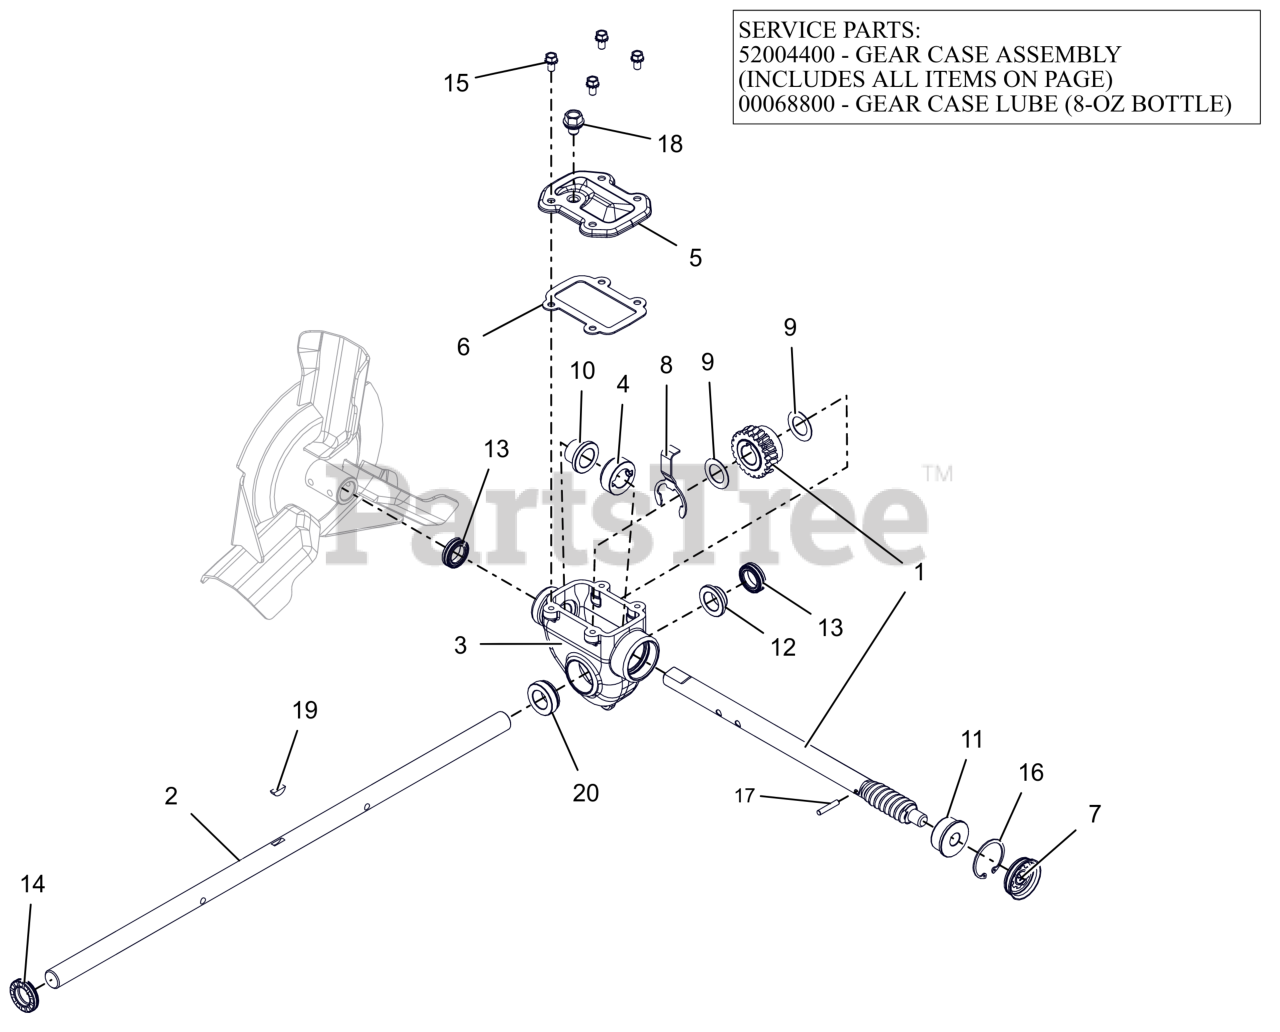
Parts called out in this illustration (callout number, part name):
1	SHAFT AND WORM GEAR ASSEMBLY
2	SHAFT, RAKE - 24" (.750 DIA)
3	GEARCASE, COMPACT MACHINED
3	GEAR CASE, 24" IRON SM TOP-LD
3	ARIENS L3 LUBE, 8 OZ BOTTLE
4	THRUST COLLAR, .75" ID SLIPFIT
5	COVER, TOP - COMPACT
6	GASKET, TOP - COMPACT GEARCASE
7	COVER, GEAR CASE 1.50"
8	BUSHING RETAINER, COMPACT
9	WSHR, FLT .760X1.225X.032 ZCC
10	BSHG-FLG .755X.878X.75X1.25
11	BSHG-FLG .503X1.303X.62X1.465
12	BSHG-FLG .755X.878X.424X1.25
13	SEAL-OIL .748X1.125X.312 TBC29
14	SEAL-OIL .748X1.300X.250 TBC29
15	BLT, SEMS .25-20X.50 G5 ZCC
16	RG-RTNG-INT 1.500X.050
17	PIN-STR .188X1.00 6150
18	SCR, .380-15X.500 W/SEAL WASHER
19	KEY-WDRF .19X.63 HRD #61
20	BSHG-FLG COMPACT, RIGHT
